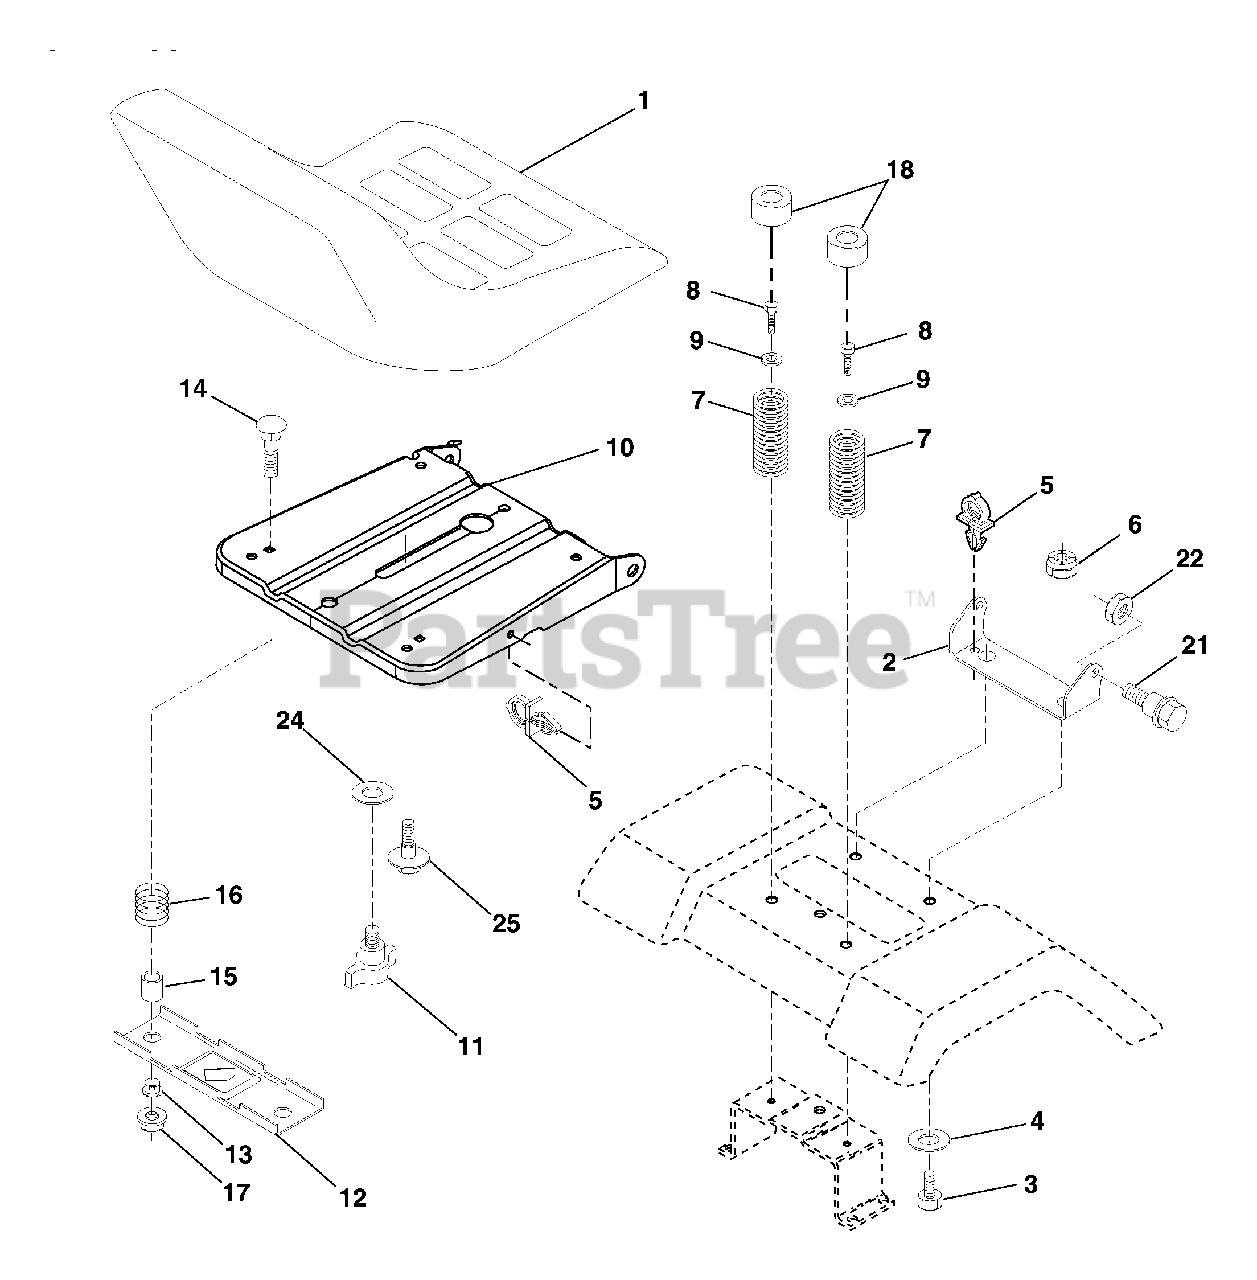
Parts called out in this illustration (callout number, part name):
1	Seat
2	Bracket Pivot Seat 8 720
3	Bolt Fin Hex 3/8-16 unc x 1
4	Washer 13/32 x 1 x 10 Ga.
5	Clip Push-In
6	Nut Hex w/Ins. 3/8-16 unc
7	Spring Seat Cprsn 2 250 Blk Zi
8	Screw 3/8-16 x 1.5 Smgml
9	Washer 13/32 x 1 x 14 Ga.
10	Pan Seat
11	Knob Seat
12	Bracket Mounting Switch
13	Bushing Snap Blk Nyl 50 Id
14	Bolt Rdhd Sqnk 1/4-20 x 1-1/2
15	Spacer Split 28 x 96
16	Spring Cprsn
17	Nut Lock 1/4 Lge Flg Gr. 5 Zinc
18	Cap Spring Seat
21	Bolt Shoulder 5/16-18 unc
22	Nut Hex Lock W/Ins 5/16-18
24	Washer 17/32 x 1-3/16 x 12 Ga.
25	Bolt Shoulder 5/16-18 x 62
